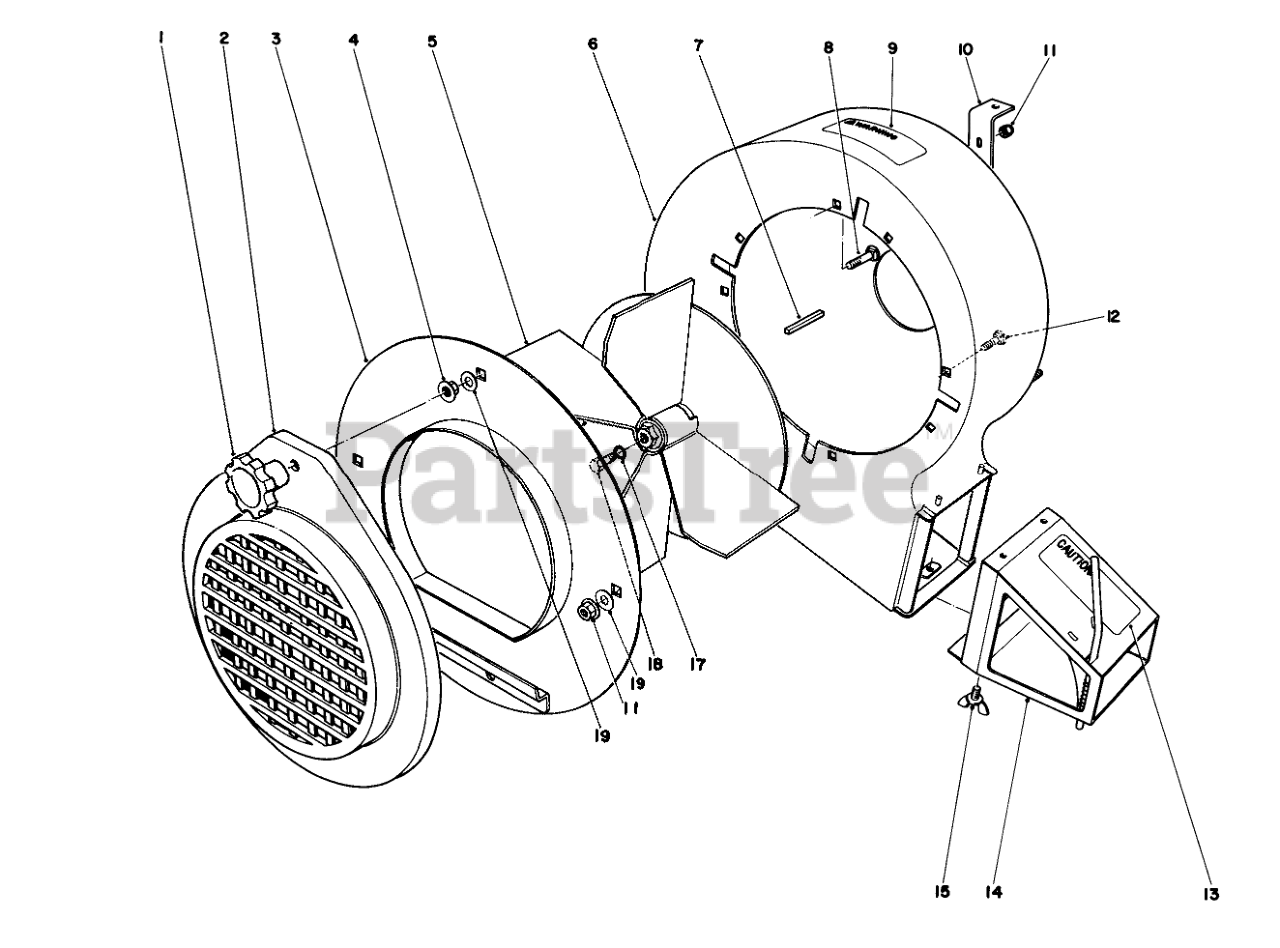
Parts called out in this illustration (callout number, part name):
2	INTAKE-BLOWER
3	Blower Cover
4	NUT-HF
5	Fan
6	Blower Housing
7	KEY-SQUARE
8	SCREW-CARR
9	WARNING DECAL
10	Mounting Bracket
11	NUT-LOCK, CONE
12	SCREW-CARR
13	EXHAUST DECAL
14	Blower, Exhaust (Incl. Ref. #13)
15	1/4 - 20 3/4 WING SCR
17	WASHER-LOCK
18	SPEC SCREW
19	WASHER-FLAT
